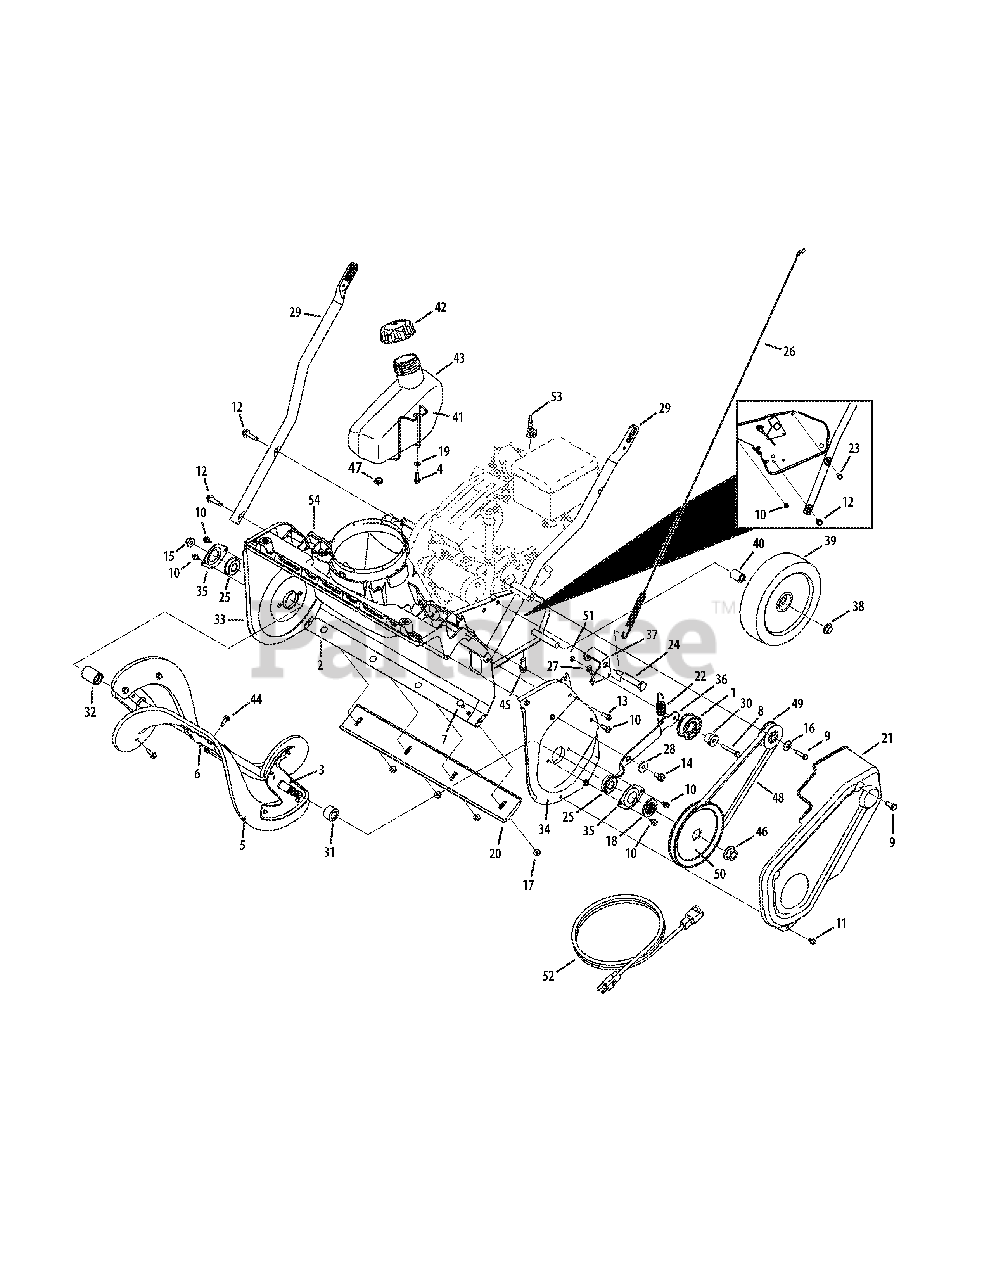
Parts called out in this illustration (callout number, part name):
1	Idler Pulley Assembly
2	Frame
3	Auger Assembly Mount
4	Screw, 1/4-10 x .625
5	Auger Replacement Kit
6	Center Auger Bracket
7	Carriage Screw, 1/4-20 x .62
8	Hex Screw, 1/4-20 x 1.50
9	Hex Lock Screw, 5/16-24 x .875
10	Hex Washer Screw, 1/4-20 x .625
11	Hex Washer Screw, 1/4-20 x .500
12	Hex Washer Screw, 5/16-18 x 1.250
13	Hex Washer Screw, 1/4-15 x .750
14	Hex Washer Screw, 5/16-18 x .75
15	Flange Lock Nut, 3/8-16
16	Thrust Washer, .330 x 1.25 x .120
17	Flange Lock Nut, 1/4-20
18	Pulley Hub
19	Washer, .265 x 1.00 x .030
20	Shave Plate
21	Belt Cover
22	Extension Spring, .70 x 3.035
23	Hex Screw, 5/16-24 x 1.25
24	Shoulder Bolt, 5/16-24 x .496 x 2.18
25	Ball Bearing, .500 x 40mm x 12mm
26	Clutch Cable
27	Drive Cable Wire Support
28	Shoulder Spacer
29	Lower Handle
30	Shoulder Spacer, .260 x .785 x .538
31	LH Auger Spacer
32	RH Auger Spacer
33	RH Auger Plate
34	LH Auger Plate
35	Bearing Cup
36	Idler Bracket
37	Cable Idler Bracket
38	Push Cap, 1/2
39	Wheel, 7"
40	Spacer, .525 x .775 x .835
41	Gas Tank Wire Support
42	Fuel Cap
43	Fuel Tank
44	Hex Washer Screw, 1/4-20 x .750
45	Hex Washer Screw, 3/8-16 x 1.000
46	Flange Nut, 7/16-20
47	Hose Clamp
48	Belt, .500 x 35.06
49	Pulley Half, .625 x 2.25
50	Pulley, 1/2 x 6.00
51	Push Nut
52	3-Prong Extension Cord
53	Choke Extension Lever (2T6)
54	Chute Adapter (2T6)
